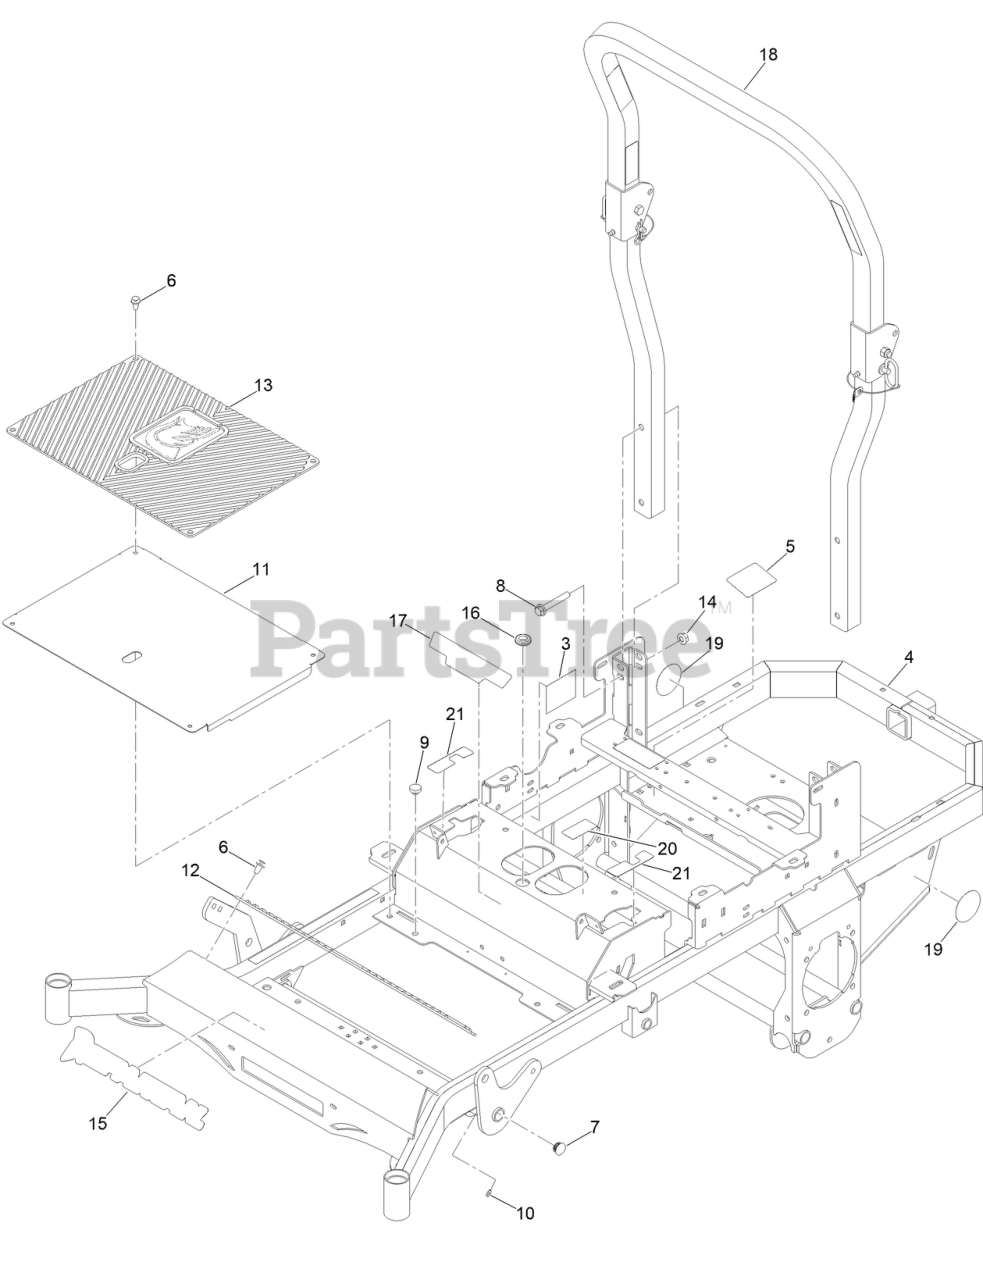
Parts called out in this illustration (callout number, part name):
3	DECAL-E P A
4	ASM FRAME W/ DECALS
5	DECAL-PUMP BELT ROUTING-PARKER
6	8MM PUSH TYPE RETAINER NYLON BLACK
7	1-1/4 IN ROUND TUBE PLUG
9	PUSH-IN RUBBER BUMPER MWR FLOOR
10	1/4 DRIVE TYPE STRAIGHT GREASE FITTNG ZC
11	MWR FLOORBOARD PAINT
12	MWR RUBBER FOOT REST MAT
13	MWR LOGO FLOOR MAT
14	1/2-13 HEX STOVER LOCKNUT GR C ZINC
15	DECAL-SPARTAN, FRONT
16	GROMMET-RUBBER
17	2022 RT-HD W/GT TRAC DECAL
18	MWR FOLD DOWN ROPS
19	MWR PARKER PUMP DECAL
20	DECAL-WEIGHT, SEAT
21	DECAL-MOTION CONTROL
